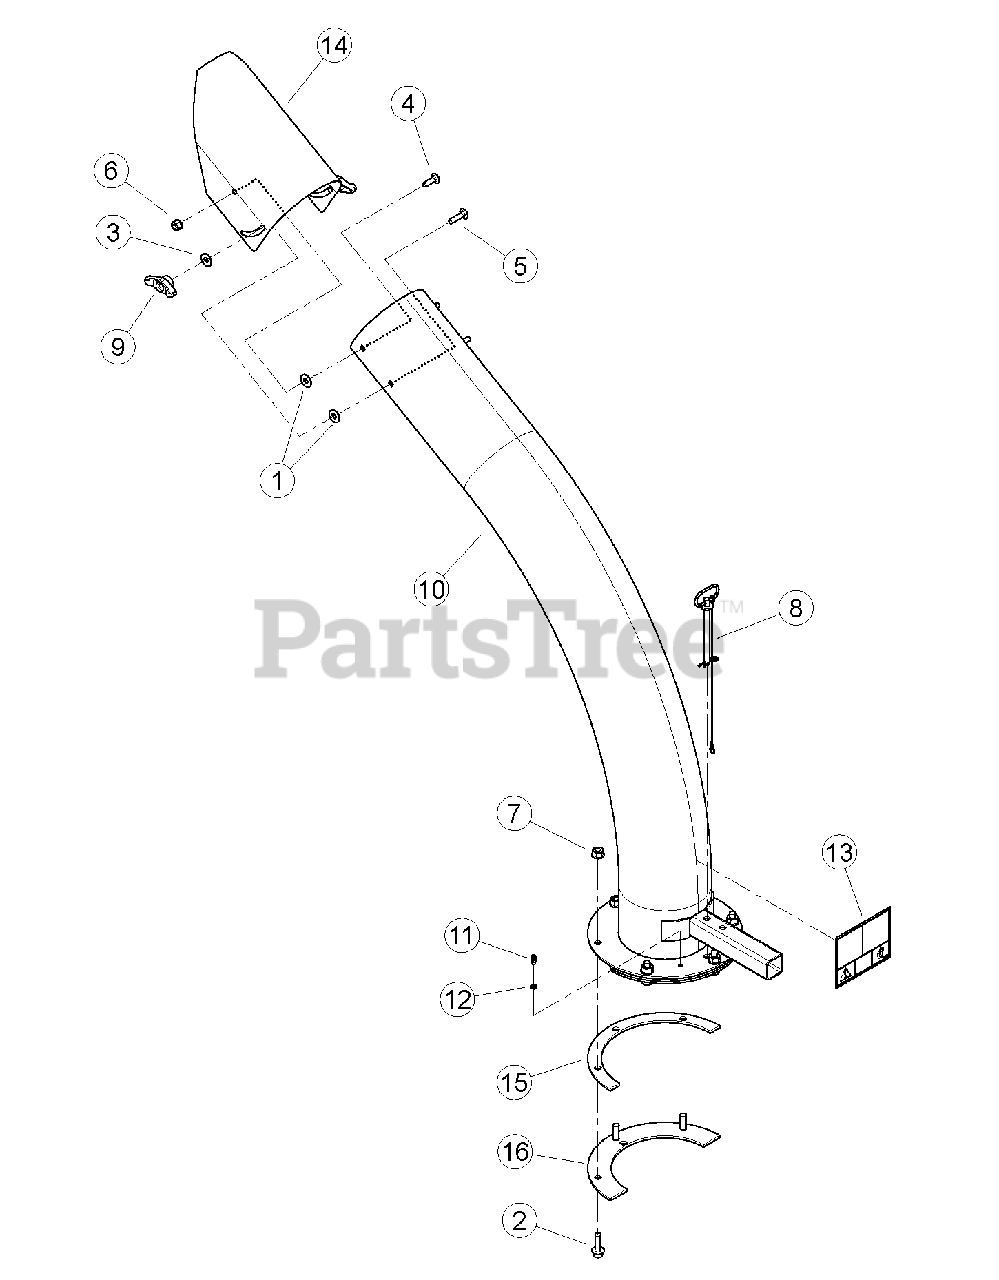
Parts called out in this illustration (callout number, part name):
1	WASHER, 3/8 FLAT
2	BOLT, 3/8 X 1-1/4 FLANGE NC
3	WASHER, 5/16 FLAT
4	BOLT, 5/16-18 X 1 GR5 CRG
5	BOLT, 5/16 X 1-1/4 GR5 CRG
6	NUT, 5/16-18 NYLOCK FLANGE
7	NUT, 3/8-16 NYLOCK FLANGE
8	PIN, 3/8" X 4.25" DISCHARGE
9	KNOB, 5/16-18 UNC TEE W/ LOCKING INSERT
10	ASSEMBLY, 6 INCH DISCHARGE CHUTE
11	FITTING, 1/4 SELF-TAP GREASE
12	WASHER, FLAT .254 X .400 X .048
13	DECAL, DISCHARGE DEBRIS & LOCK
14	DEFLECTOR, BLOWER VAC DISCHARGE
15	SPACER, DISCHARGE PIVOT
16	RING, DISCHARGE CLAMP
